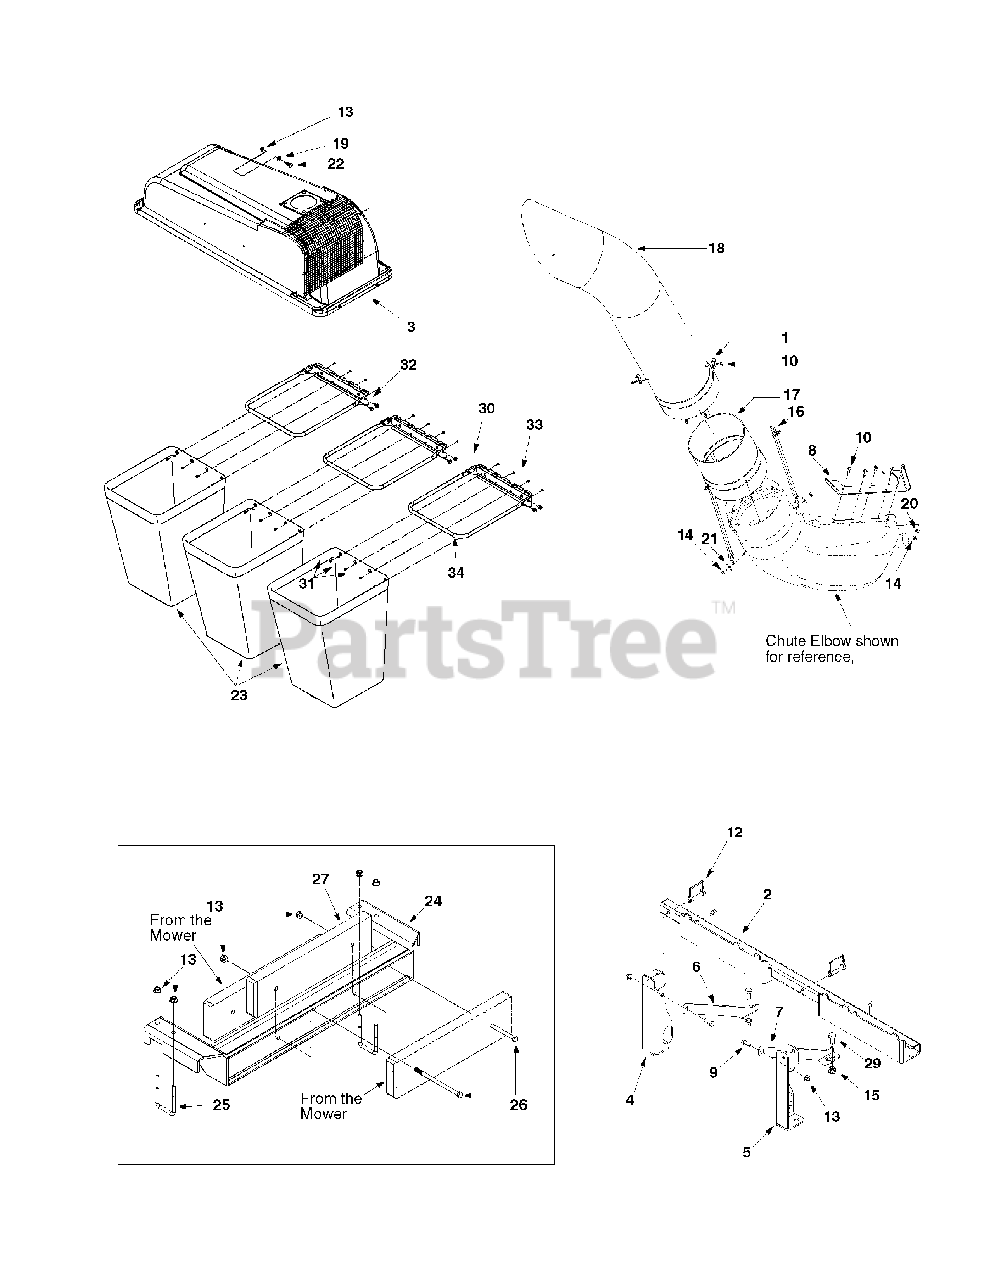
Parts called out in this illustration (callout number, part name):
1	Retainer Hook
2	Catcher Support Bracket
3	Catcher Cover
4	Upright Mounting Bracket LH
5	Upright Mounting Bracket RH
6	Upright Gusset LH
7	Upright Gusset RH
9	Hex Bolt 3/8-16 x 1.0"
10	Hex Bolt 1/4-20 x 0.620"
11	Carriage Bolt 3/8-16 x 1.25"
13	Top Lock Flange Nut 3/8-16
14	Flange Lock Nut 1/4-20
15	Lock Nut 1/2-13
16	Chute Strap
17	Extension Tube
18	Chute Tube
19	Belleville Washer
20	Bell Washer
21	Flat Washer
22	Shoulder Screw 3/8-16
23	Triple Grasscatcher bag
24	Weight Bar Bracket
25	U Bolt 3/8-16 x 1.5"
26	Hex Bolt 3/8-16 x 6.25"
28	Carriage Bolt 3/8-16
29	Hex Screw 1/2-13
30	Bag Frame Hangar Bracket
31	Machine Screw #10-24 x .50
32	Screw 5/16-18 x .625
33	Hex Nut 10-24
34	Grass Bag Frame
